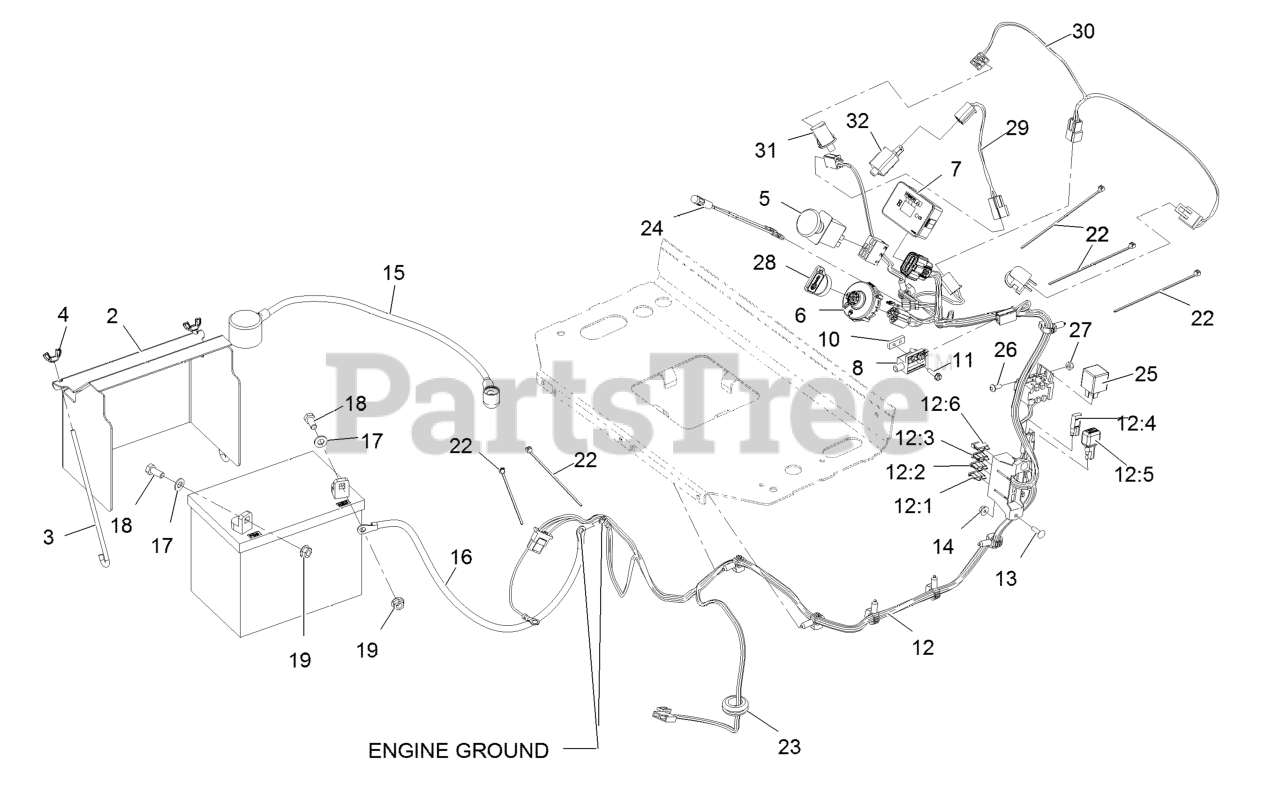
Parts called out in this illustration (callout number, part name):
2	COVER-BATTERY
3	BOLT-HOLDDOWN
4	WINGNUT
5	SWITCH-PTO, ON-ON
7	MODULE-HOUR METER
8	SWITCH-CLOSED, NORMALLY
10	PLATE-TAPPED
11	SCREW-HWH
12	HARNESS-WIRE, EFI
12:1	FUSE-BLADE, 30 AMP
12:2	FUSE-BLADE, 25 AMP
12:3	FUSE-BLADE, 10 AMP
12:6	FUSE-BLADE, 15 AMP
13	SCREW-CARR
15	CABLE-BATTERY, POSITIVE
16	CABLE-BATTERY, BLACK
17	WASHER-PLAIN
18	SCREW-HH
19	NUT-HHF, SMOOTH
22	TIE-CABLE
23	GROMMET
24	INDICATOR-LED, RED
26	SCREW-PPH
27	NUT-LOCK, NI
28	KEY-IGNITION
29	HARNESS-NEUTRAL
30	HARNESS-OPC
31	SWITCH-BAIL
32	SWITCH-OPEN, NORMALLY
